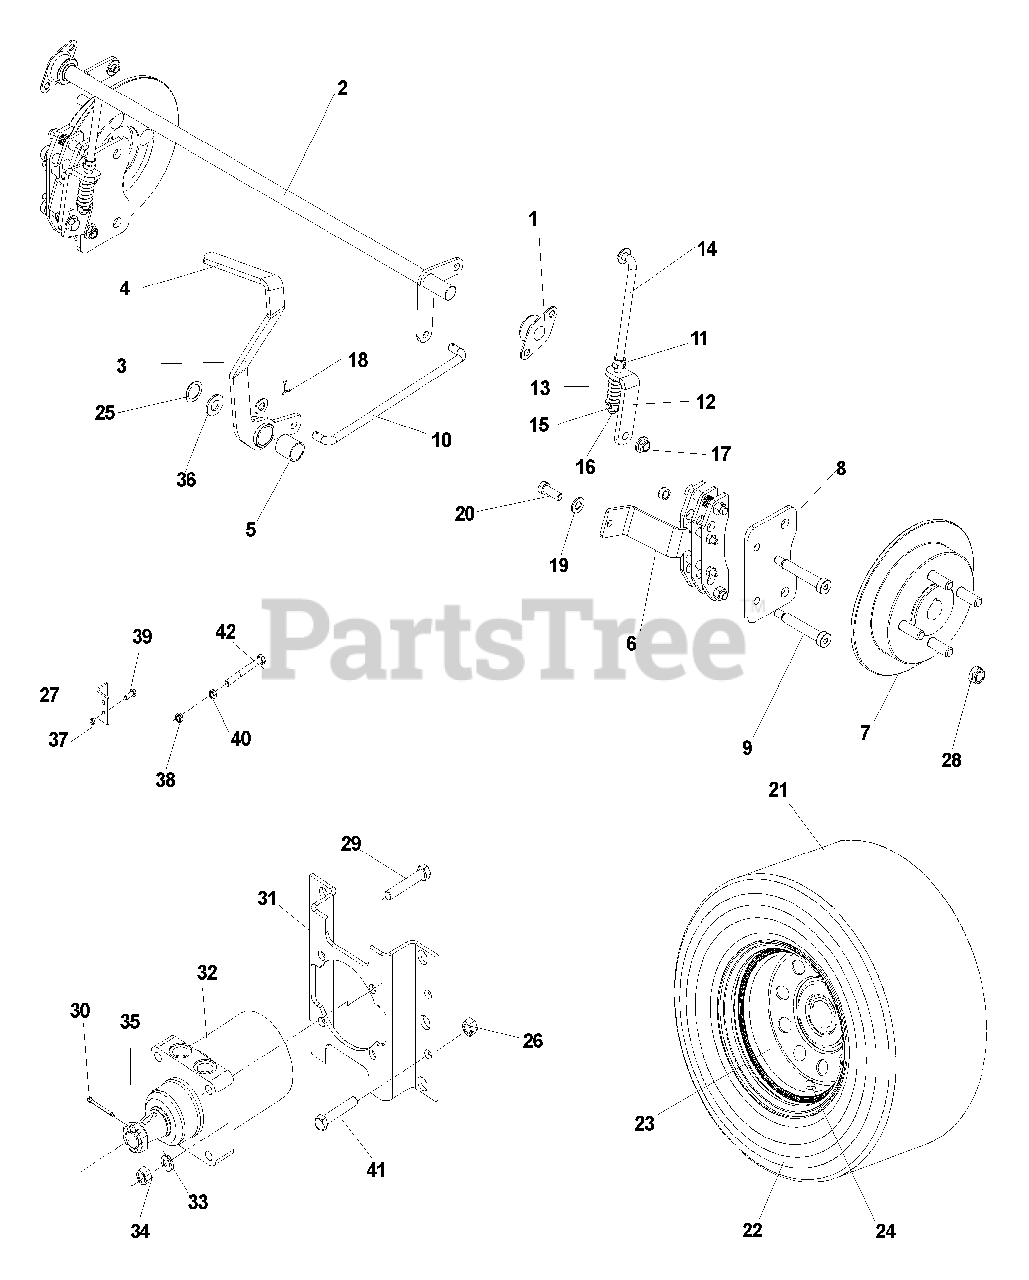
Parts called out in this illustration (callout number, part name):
2	BRAKE CROSS SHAFT
3	BRAKE LEVER
4	GRIP PARK BRAKE
6	CALIPER
8	PLATE, BRAKE
9	SCREW, 3/8-16 X 2 1/2, SKT HD
10	LINKAGE, BRAKE
11	NUT, 3/8-24, JAM
14	LINKAGE, REAR BRAKE
15	WASHER, 3/8, SAE
16	NUT, 3/8-24, CENTERLOCK, GR5
17	NUT, 3/8-16, THIN NYLOC
18	PIN COTTER, 3/32 X 3/4
19	WASHER, 3/8, SAE
20	HCS, 3/8-16 X GR5
21	TIRE
23	RIM
24	VALVE STEM
25	RING, RETAINING, EXT 7/8
26	NUT, 1/2-13, NYLOC
28	NUT, 1/2-20, LUG
29	HCS, 1/2-13 X 2 3/4, GR5
30	PIN COTTER
31	MOTOR STANDOFF
32	WHEEL MOTOR
33	LOCKWASHER, 1/2
34	NUT,1/2-13
35	HEX SLOTTED NUT
37	NUT, 1/4-20, NYLOC
38	NUT, 3/8-16, NYLOC
39	HCS, 1/4-20 X 3/4, GR5
40	NUT, 3/8-16, WHIZLK
41	BOLT, 1/2-13 X 1 1/4, WHIZLK, SP
42	HCS, 3/8-16 X 2 1/2, GR5
